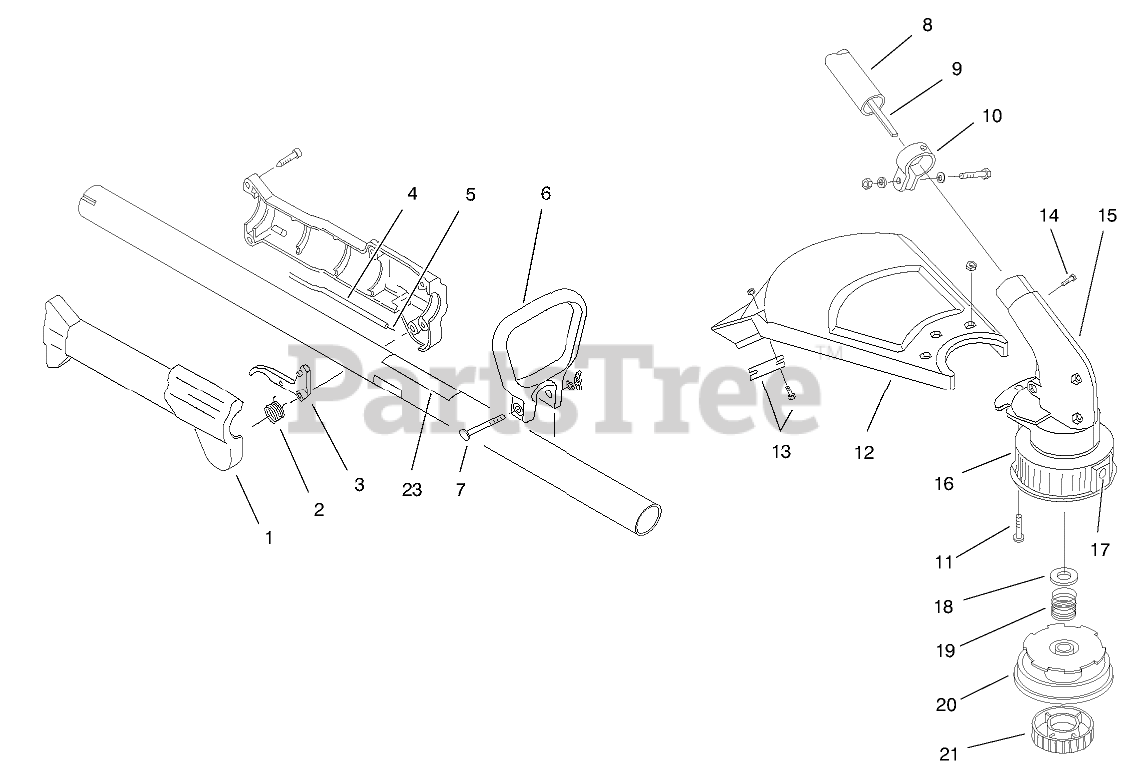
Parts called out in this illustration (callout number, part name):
1	Throttle Housing & Trigger Asm.
2	THROTTLE TRIGGER SPRING
3	TRIGGER - THROTTLE
4	HOUSING-CABLE
5	THROTTLE CABLE WIRE
6	D-HANDLE
7	HARDWARE - D-HANDLE
8	ASM - SHAFT HOUSING
9	Drive Shaft
10	CLAMP ASM - UPPER
11	ASM - GUARD MTG SCREW
12	Guard and Blade Asm.
13	BLADE ASM
14	ANTI-ROTATION SCREW
15	ASM - GEAR BOX
16	OUTER SPOOL EYELET ASM
17	EYELET
18	RETAINER WASHER(SET OF 10)
19	SPRING
20	REEL - INNER
21	Assy.-Bump Head
23	Decal-Safety Symbol
